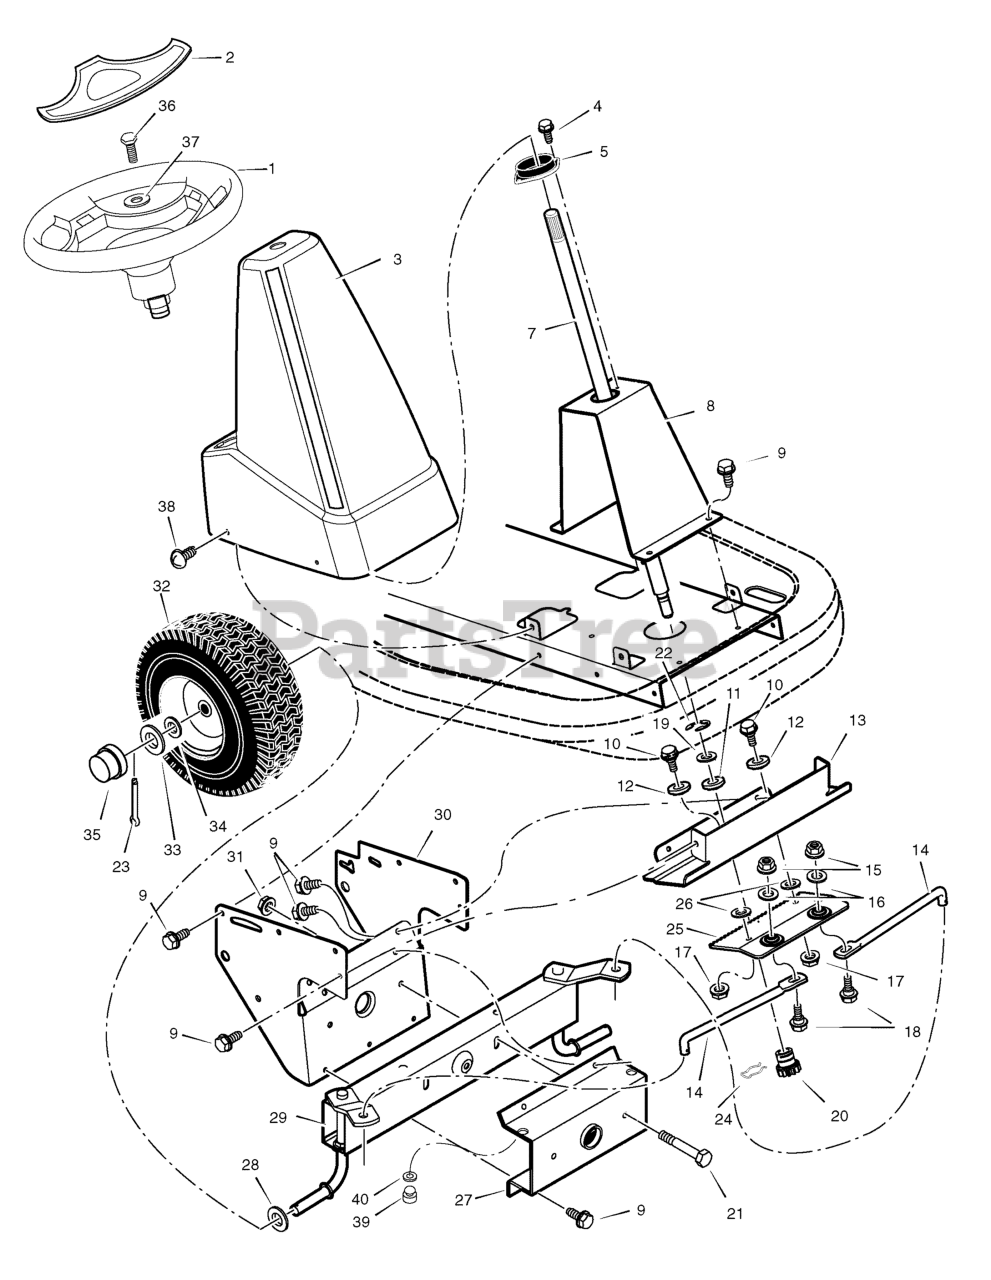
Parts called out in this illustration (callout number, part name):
1	Wheel, Steering
2	Cap, Steering (Black)
3	Console, High (Black)
4	Screw
5	Bearing, Upper Steering
7	Shaft, Steering
8	Support, Steering
10	Bolt, Shoulder
11	Bearing, Lower Steering
13	Plate, Gear Mounting
15	Nut, Flange
16	Washer
17	Nut, Flange
18	Bolt, Hex
20	Gear, Pinion
21	Bolt, Hex
22	E-Ring, Retainer
23	Pin, Cotter
24	Retainer, Spring
25	Rack, Steering
27	Bracket, Axle Front
29	Axle & Spindle Assembly
30	Bracket, Support
31	Nut, Flange
32	Wheel, Front
35	Cap, Hub
36	Screw, Hex
37	Washer
